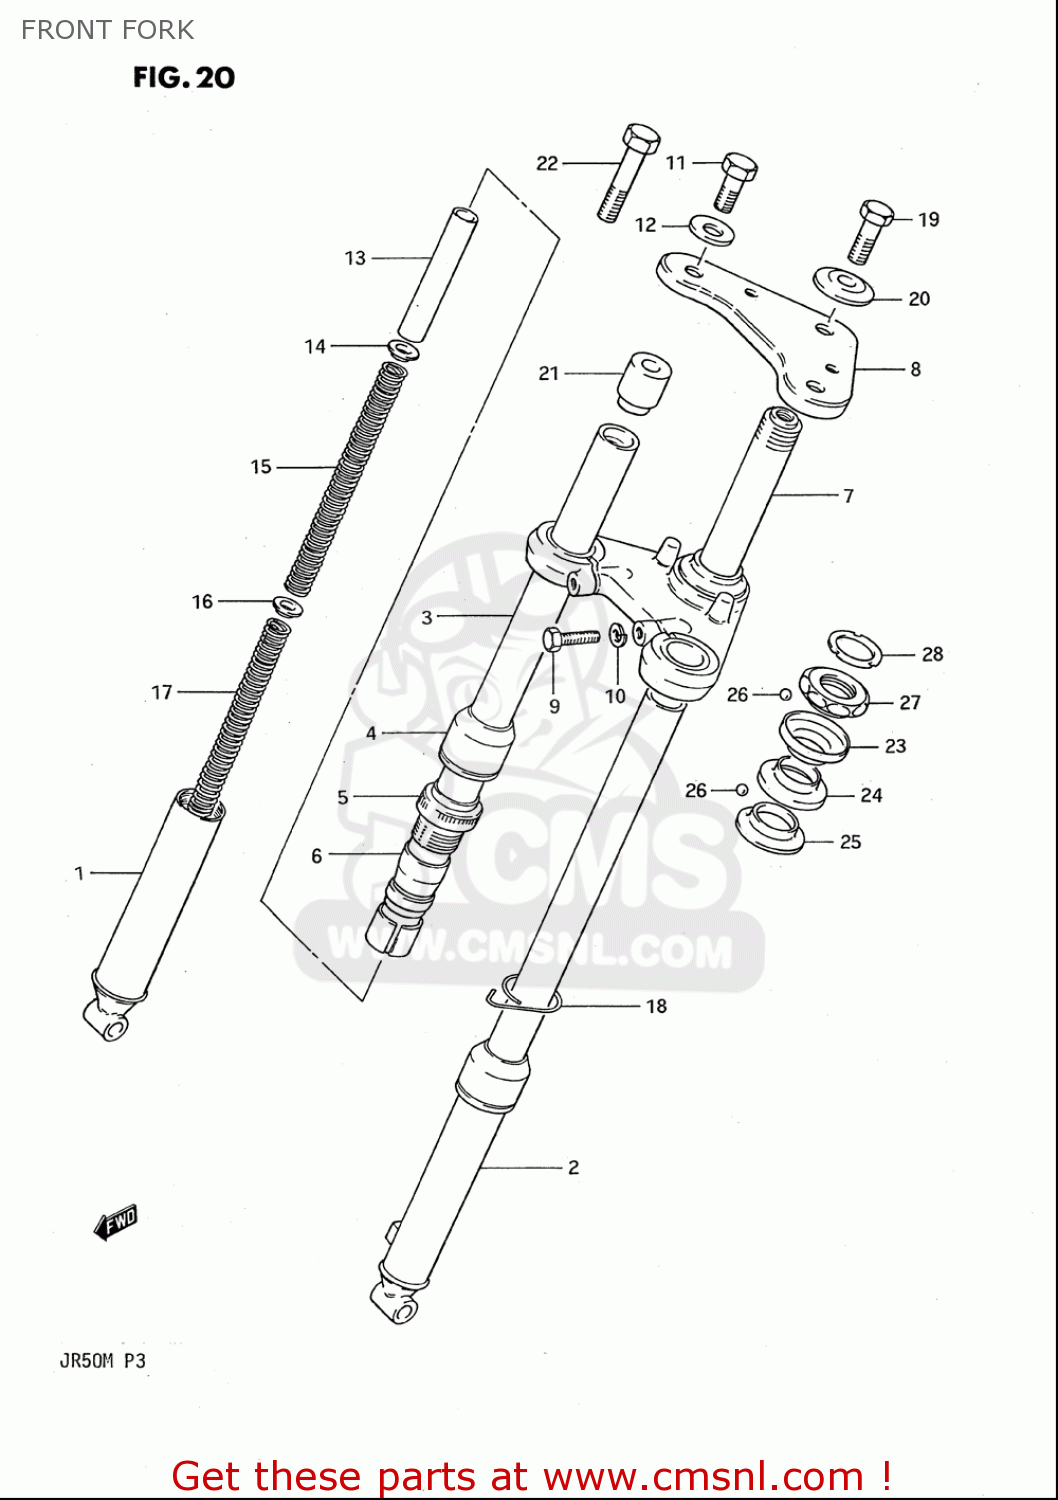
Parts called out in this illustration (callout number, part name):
1	TUBE,OUTER,R
2	TUBE,OUTER,L
3	TUBE,INNER
4	SEAL,DUST
5	NUT,OUTER
6	STOPPER
7	STEM,STEERING
8	HEAD,STEERING STEM
9	BOLT
10	WASHER,LOCK
11	BOLT
12	WASHER,STEERING STEM HEAD
13	SPACER
14	GUIDE,SPRING
15	SPRING,NO.1
16	GUIDE,SPRING NO.2
17	SPRING,NO.2
18	CLIP
19	BOLT
20	WASHER(33.5X10.5X4.2)
21	SPACER,FR FORK INNER TUBE
22	BOLT(10X52)
23	RACE,STEERING
24	RACE,STEERING INNER LWR
25	RACE,STEERING,OUTER,LOWER
26	BALL
27	RACE,STEERING OUTER UPR
28	NUT
